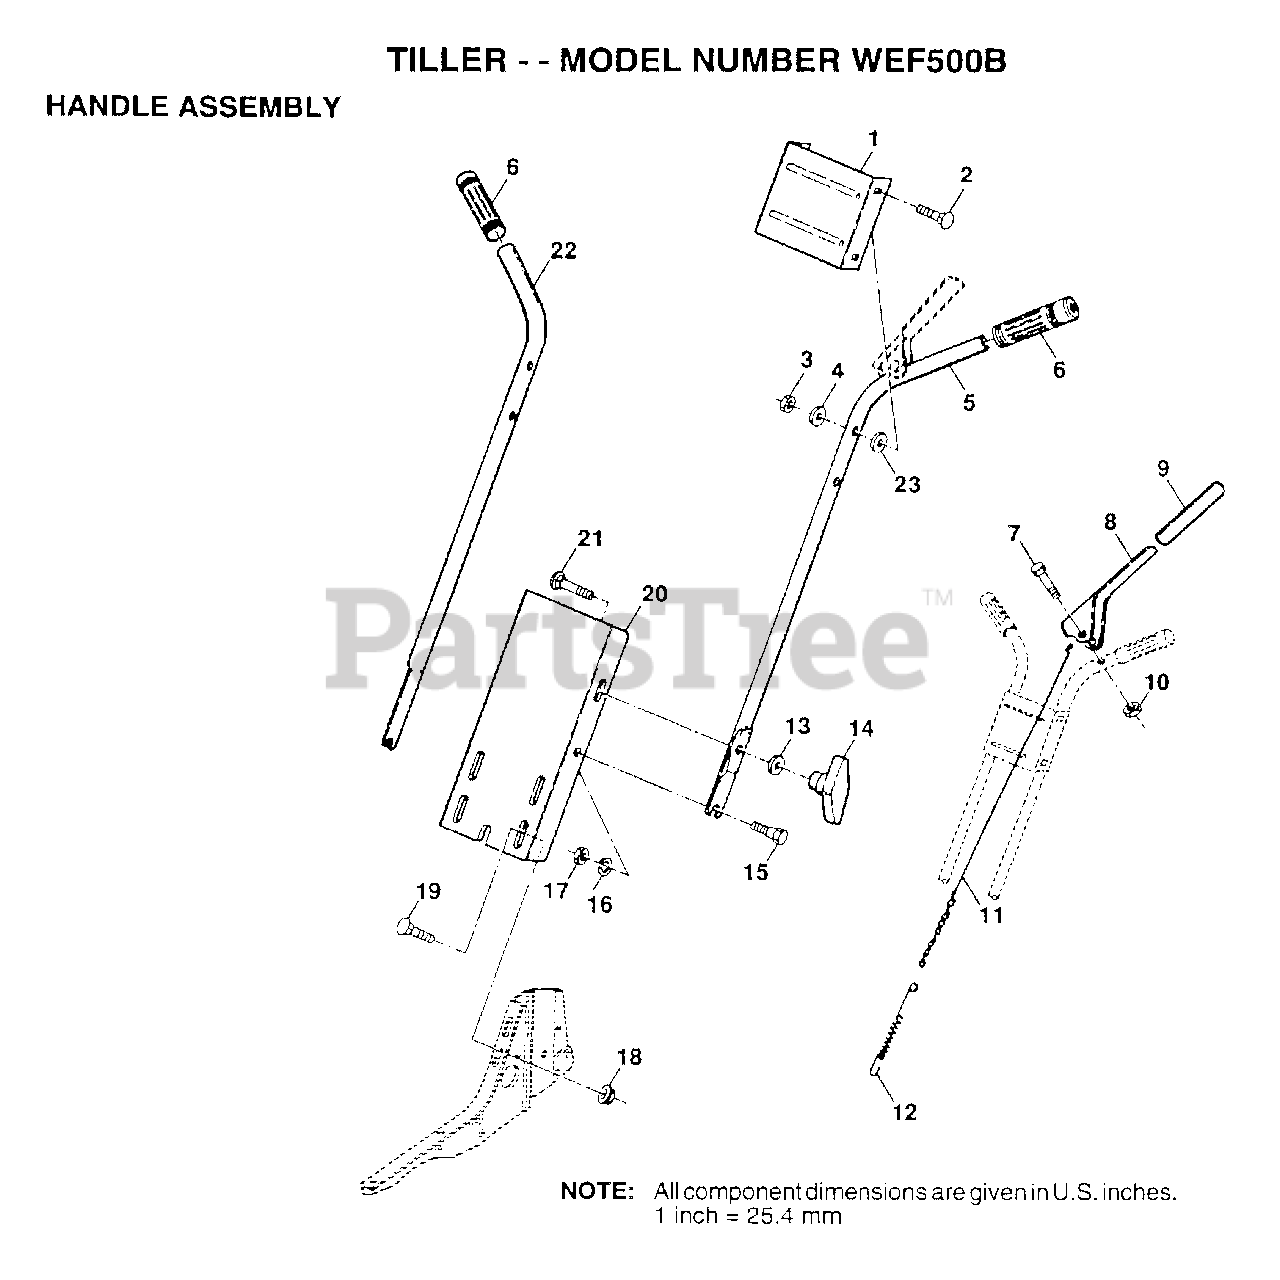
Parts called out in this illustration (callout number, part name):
1	PANEL.CNTRL.HDLE.
2	BOLT
4	WASHER
6	GRIP NUB DOUBLE
7	BOLT.HEX.5/16-1.5
9	GRIP T
12	SPRING EXT TI
13	WASHER
14	KNOB HANDLE
16	LOCKWASHER
17	NUT.HEX.5/16-18
18	NUT
19	BOLT
20	PANEL.HANDLE.TILL
21	BOLT CRT
23	WASHER
